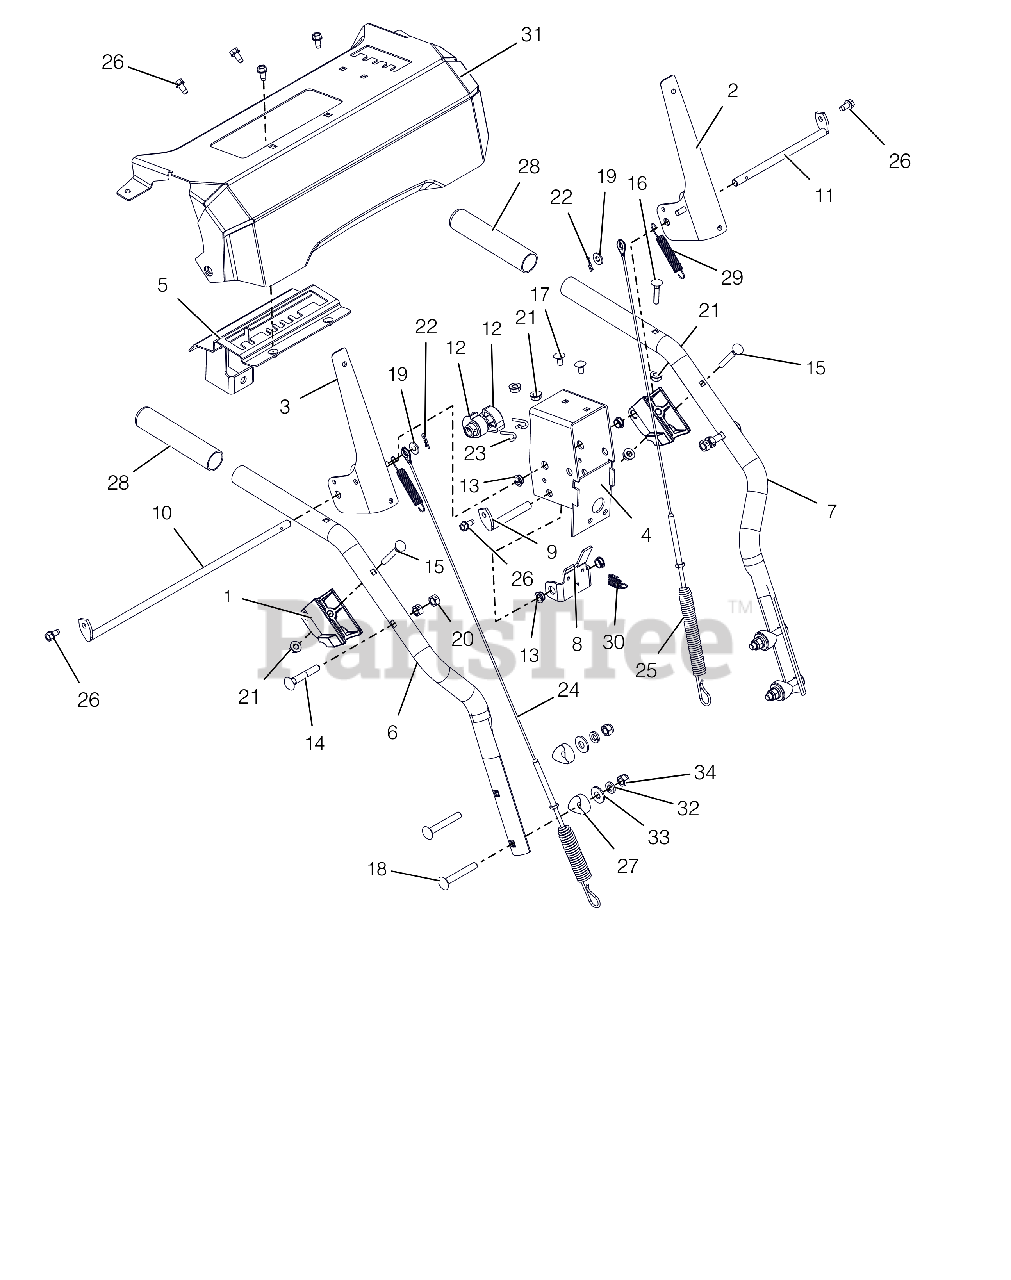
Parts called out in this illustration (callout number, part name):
1	BLOCK, CLUTCH PADDLE
2	LEVER, CLUTCH-LH
3	LEVER, CLUTCH-RH
4	WELDMENT, BRACKET INTERLOCK
5	WELDMENT, DETENT PLATE-COMPACT
6	HANDLEBAR, UPPER - RH
7	HANDLEBAR, UPPER - LH
8	BRACKET, INTERLOCK ARM
9	ROD, PIVOT - INTERLOCK
10	ROD, PADDLE MOUNT - LONG
11	ROD, PADDLE MOUNT - SHORT
12	CAM, INTERLOCK
13	BUSHING, POLYLINER-.38 SNAPIN
14	BLT-RDHDXLSQNK .31-18X2.0 G5YZ
15	BLT-RDHDXLSQNK .25-20X2.0 G5YZ
16	BLT-RDHDXLSQNK.25-20X1.25 G5ZC
17	@BLT-RDHDSQNK .25-20X.50 G5YZ
18	@BLT-RDHDSQNK .31-18X2.25 G5YZ
19	@WSHR-FL-STL.281X.62X.065 YWZC
20	@NUT-LK-CTR .31-18 YWZC
21	@NUT-LK-TOP-FLG .25-20 YWZC
22	PIN-HAIR INT .06X.18X.77
23	PIN, SPRING CLIP
24	CABLE, AUGER (DELUXE & PRO)
25	CABLE, UPPER TRACTION
26	SCR-TAP .25-20X.50 HWH TR YWZ
27	SPACER, HANDLEBAR
28	GRIP,HANDLE-GRAY
29	SPRING, EXTENSION
30	SPRING-EXT .047X.438X1.45
31	CONTROL PANEL W/DECAL, BRUSH
32	WSHR-LK .312X.097 HVY YWZC
33	@WSHR-FL-STL.38X.875X.083 YWZC
34	@NUT-LK-NYL .312-18 YWZC
